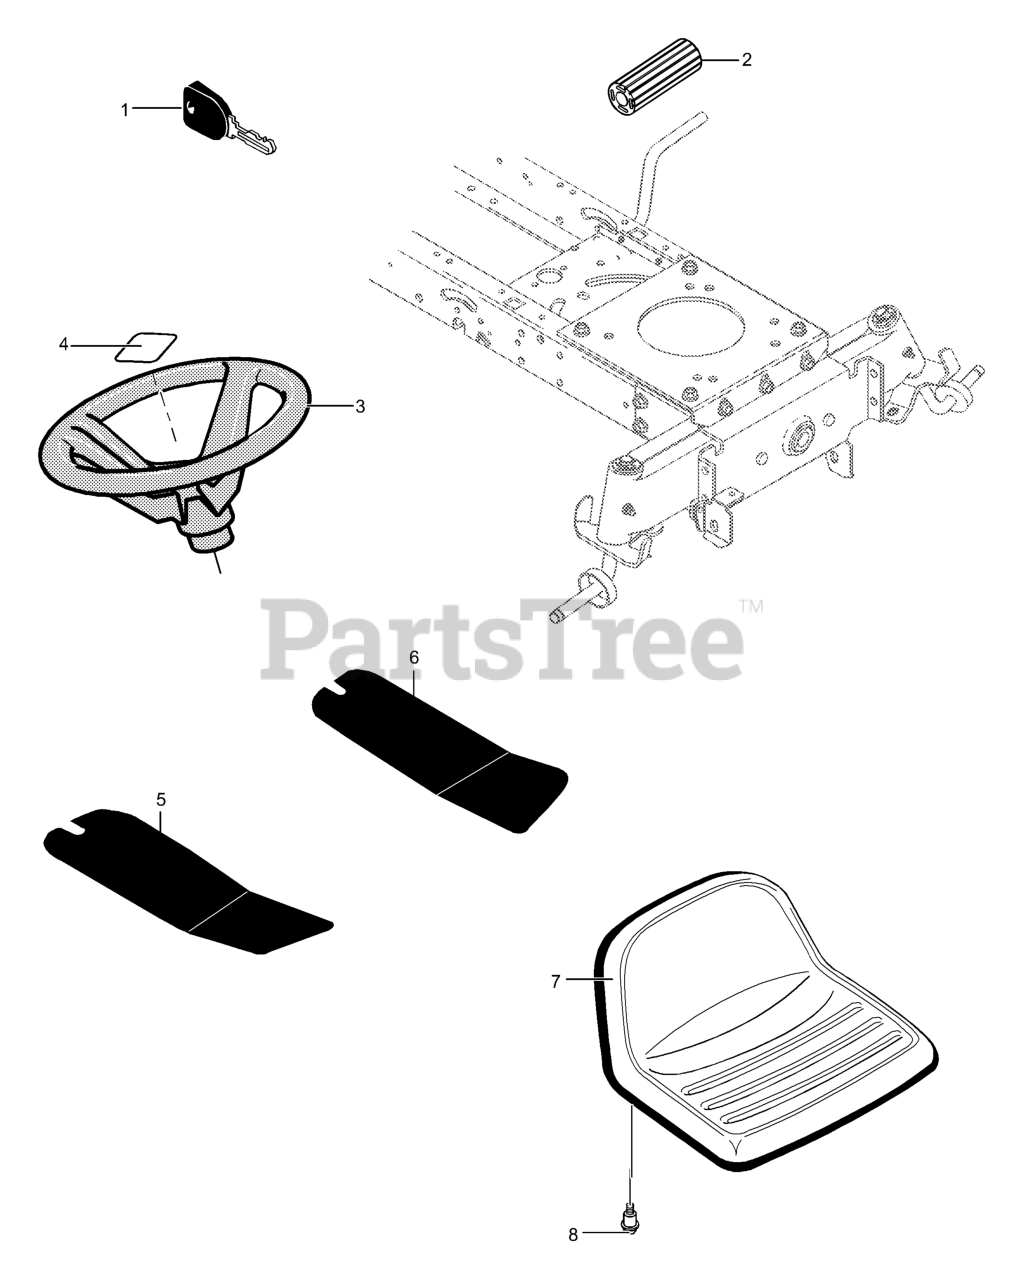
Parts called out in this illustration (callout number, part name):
1	Ignition Key
2	Cover, Pedal Brake/Clutch
3	Steering Wheel
4	Insert, 4-Spoke
5	Footrest Pad RH
6	Footrest Pad LH
7	Seat
8	Shoulder Bolt 5/16-18
